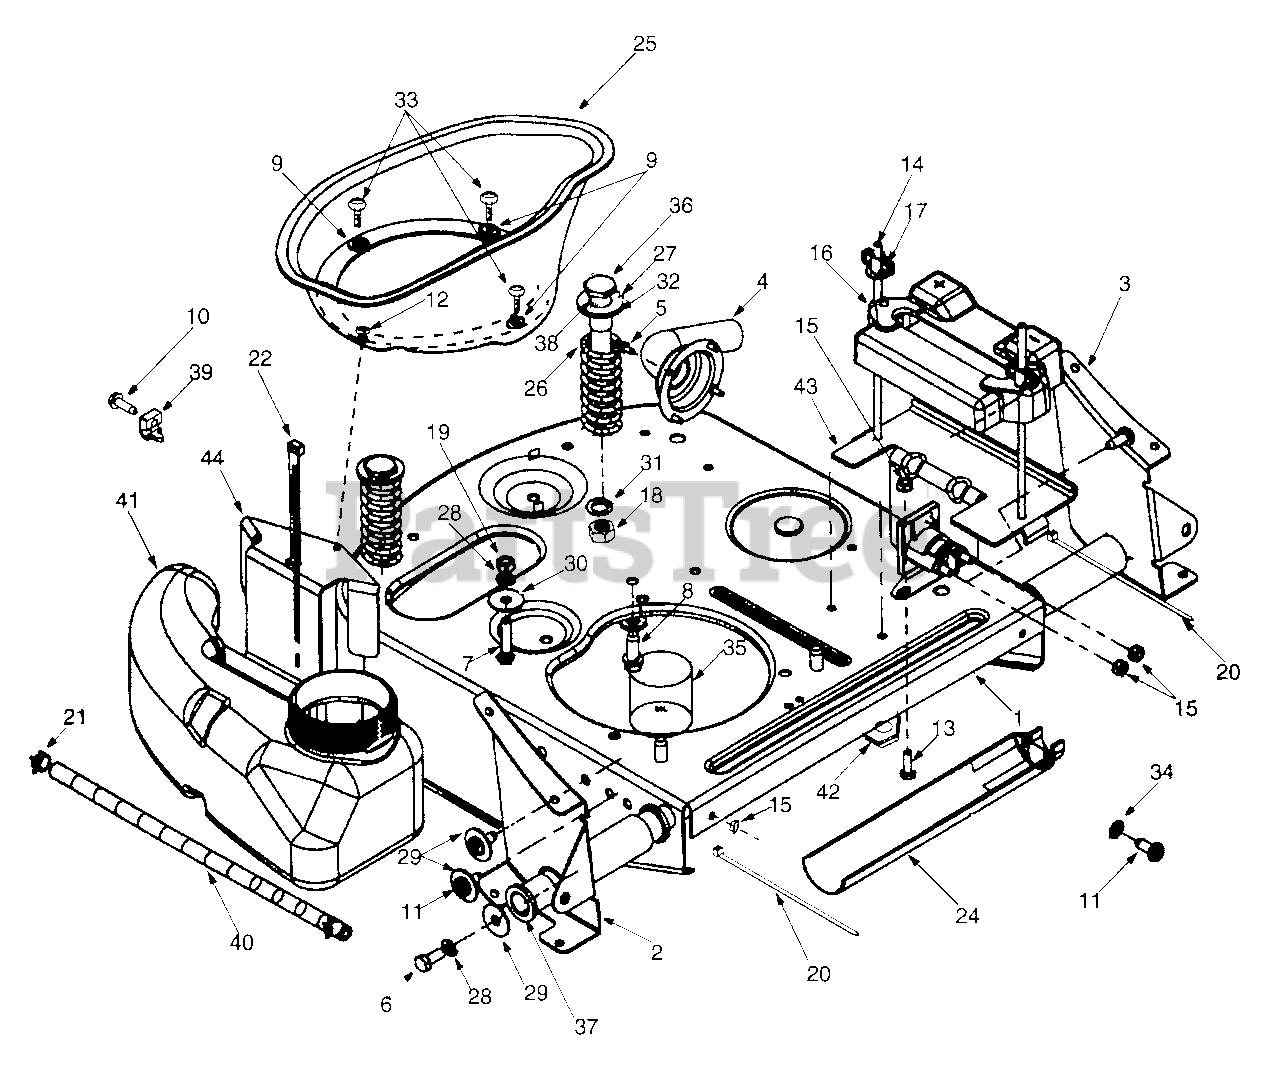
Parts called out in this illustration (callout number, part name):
5	Hex Fl. Screw #8-32 x 0.375
6	Hex Screw 5/16-24 x .75" Gr. 5
7	Hex Screw 5/16-24 x 1.5" Gr. 5
8	Hex Washer Head TT Screw 3/8-16 x 1.0"
9	Hex Slot Sems Screw #10-32 x 0.38
10	Hex Washer TT Screw #10-32 x 0.625"
11	TT Screw 5/16-18 x 0.75"
12	Machine Screw #10-32 x 0.5"
13	Hex Screw 1/4-20 x 0.75"
14	Battery Hold-Down Rod
15	Hex Sems Nut 1/4-20
16	Battery Cover
17	Wing Nut with Bell Washer
18	Hex Nut
19	Hex Nut 5/16-24 Gr. 5
20	Cable Tie
21	Hose Clamp
22	Cable Tie
24	Oil Drain Sleeve
25	Engine Duct
26	Compression Spring
27	Rubber Washer
28	Lock Washer
29	Flat Washer
30	5/16 Washer
31	Lock Washer
32	Flat Washer
33	Flat Washer
34	Lock Washer
35	Motor Oil
36	Shoulder Screw
37	Flange Bearing
38	Flange Bearing
39	Throttle Casing Clamp
40	Fuel Line Hose
41	Fuel Tank
